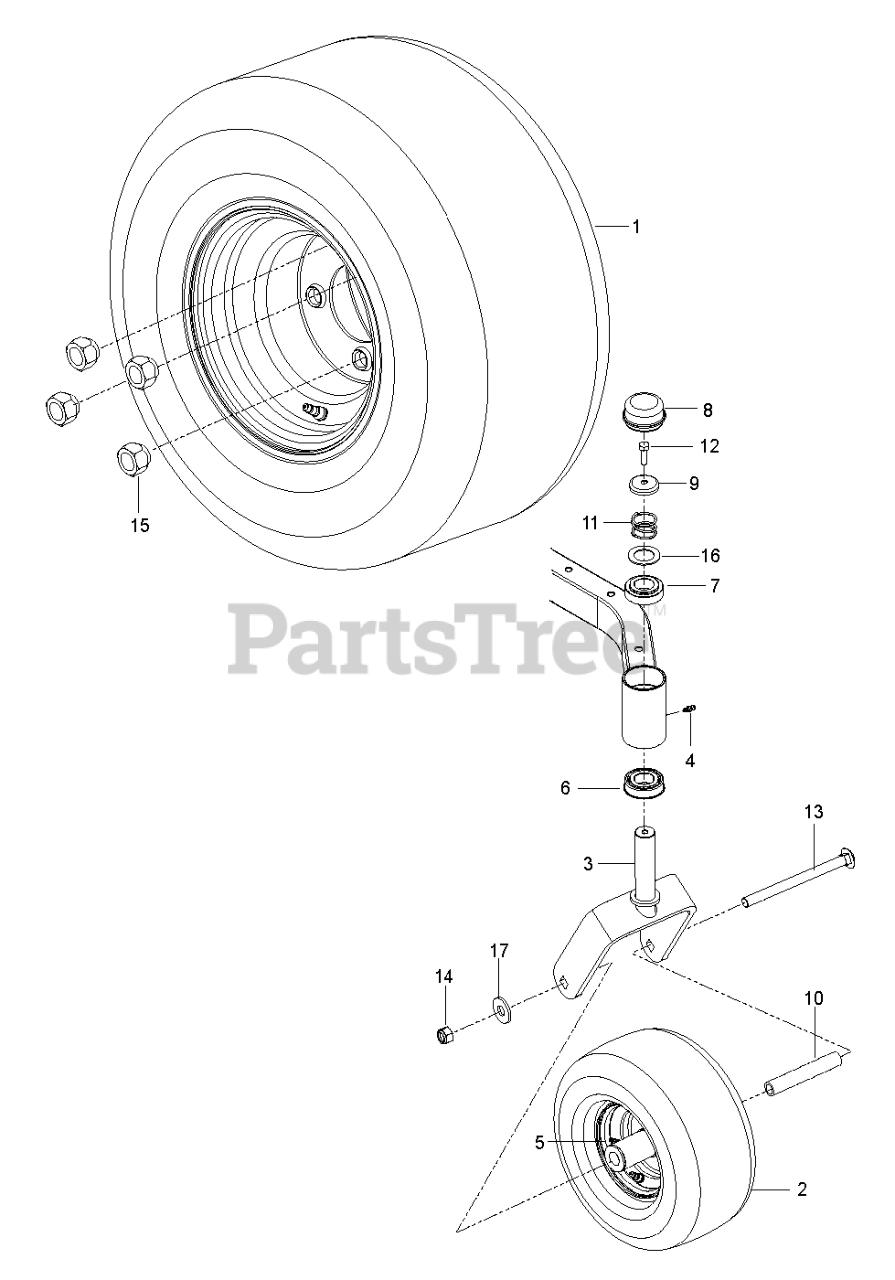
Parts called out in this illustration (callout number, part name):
1	WHEEL.A500.18 X 9.5-8.SILVER
2	WHEEL ASSY, WIDE, RZ
3	YOKE.PNT.CASTER.ORG
4	ZERK, 3/16, DRIVE IN
5	ZERK
6	BEARING FLANGED
7	BUSHING, CASTER
8	GREASE CAP
9	CASTER.PLUG
10	SPACER.PIVOT
11	SPRING, CASTER
12	5/16-18X1 HHB G5W/NY
13	RHSNB 1/2-13 X 7.5
14	NUT. 1/2-13 HEX CNTRLK GR 5 ZD
15	NUT.1/2-20.UNF-2B.GR.8.YL
16	WASHER, 1.025 ID X 1.64
17	WASHER.9/16 X 1 3/8 X 12 GA.
